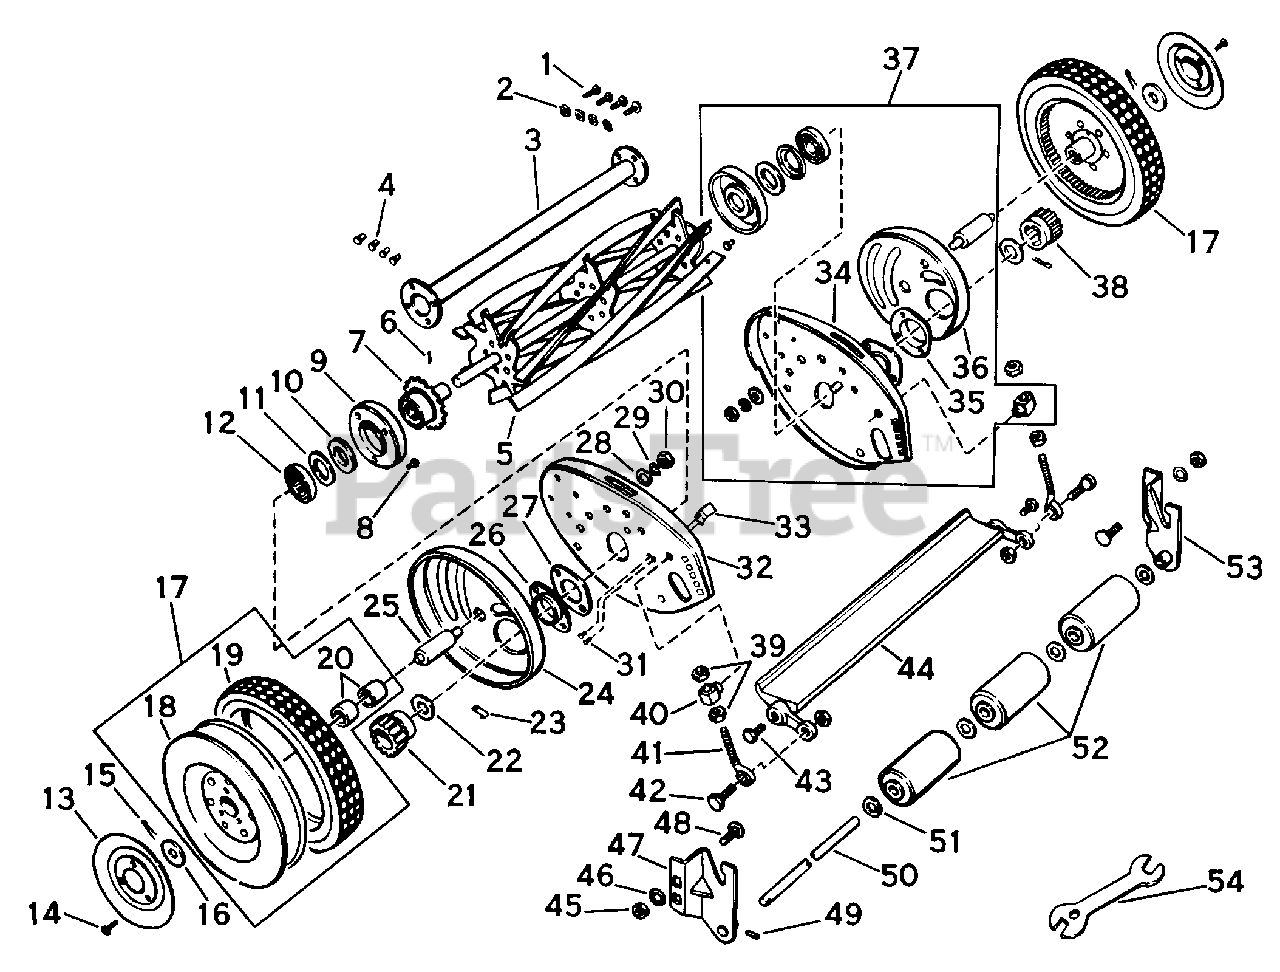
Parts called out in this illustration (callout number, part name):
1	Screw (#10-32 x 7/16 Sems Ph. Rd. Hd.)
2	Nut (#10-32 Sq.)
3	Spacer Tube Assembly-18"
3	Spacer Tube Assembly-21"
4	Rivet
5	Reel Assembly-18"
5	Reel Assembly-21"
6	Roll Pin
7	Sprocket, Anti-wind Cub and Hub Assembly
8	Rivet
9	Retainer
10	Felt Washer
11	Felt Retainer
12	Bearing
14	Screw (#10-32 x 3/8 Ph. Rd. Hd.)
15	Cotter Pin (1/8 x 5/8)
16	Washer
17	Wheel and Tire Assembly
18	Drive Wheel Less Tire
20	Bearing
21	Pinion Gear-L.H.
22	Felt Washer
24	Gear Housing-L.H.
26	Pinion Housing-L.H.
27	Retainer
28	Washer
29	Lockwasher
30	Nut (3/8-24 Hex.)
31	Screw (#10-32 x 3/8 Sems)
32	End Plate with Trunnions-L.H.
33	Scraper
34	End Plate with Trunnions-R.H.
35	Pinion Housing-R.H.
36	Gear Housing-R.H.
37	End Plate Assy. Complete-R.H.
37	End Plate Assy. Complete-L.H.
38	Pinion Gear-R.H.
39	Nut (3/8-24 Hex.)
40	Trunnion
42	Screw
43	Screw
44	Cutter Bar Assembly-18"
44	Cutter Bar Assembly-21"
45	Nut (5/16-18 Hex.)
46	Washer
47	Roller Bracket Assy-L.H.
48	Bolt (5/16-18 x 5/8)
49	Roll Pin
50	Roller Shaft-18"
50	Roller Shaft-21"
52	Roller Assembly-18"
52	Roller Assembly-21"
53	Roller Bracket Assy.-R.H.
54	Wrench
